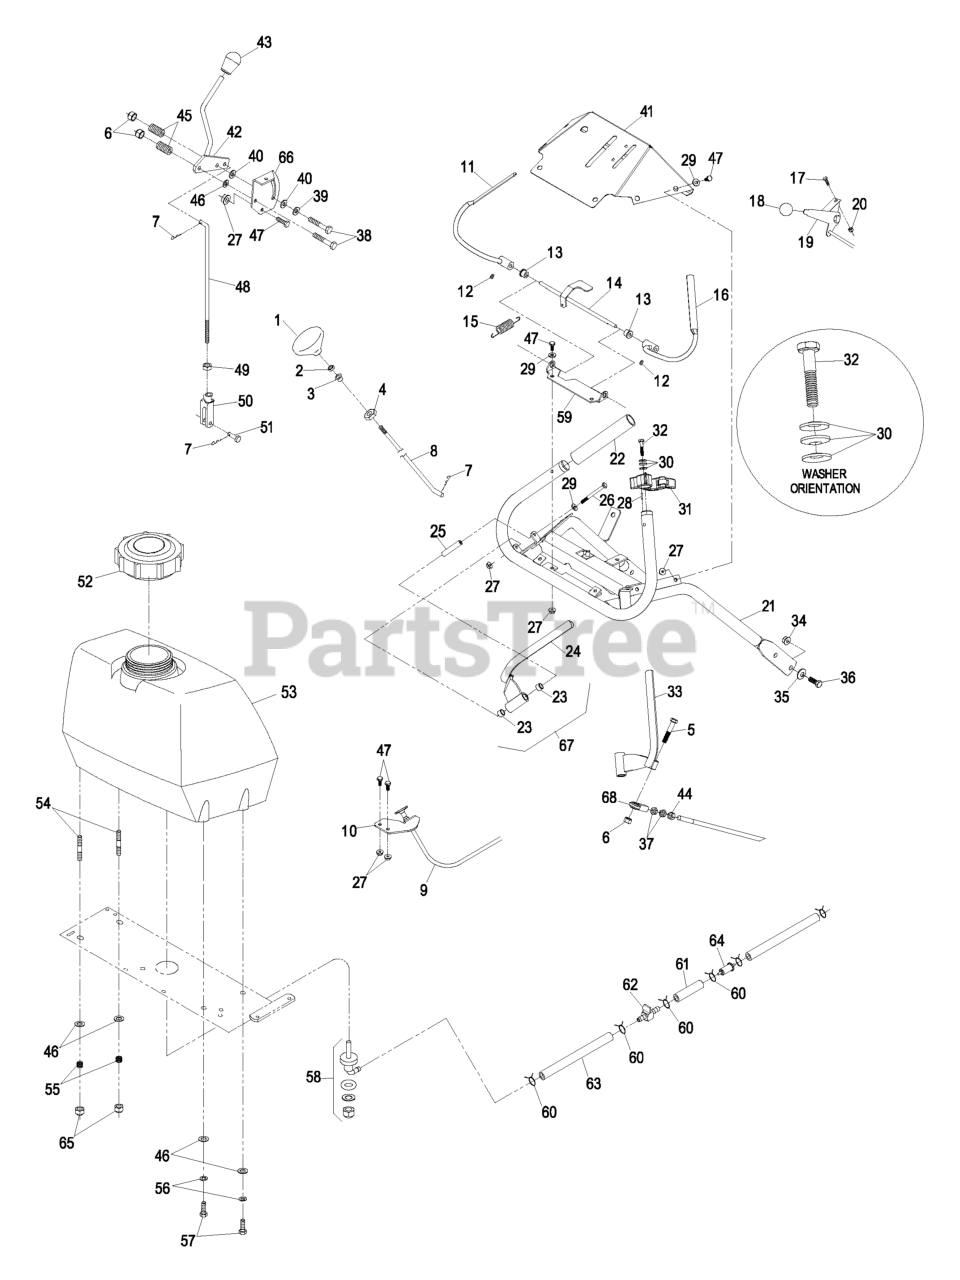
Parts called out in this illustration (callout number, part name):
1	KNOB-PUSH / PULL
2	NUT-JAM
3	BEARING-NYLON
4	NUT-PUSH
5	SCREW-HH
6	NUT-LOCK, NI
7	PIN-COTTER
8	LINKAGE,BLADE PUSH/PULL
9	CABLE-CHOKE
10	BRACKET-CABLE, CHOKE
12	SCREW-SET
13	BUSHING-NYLON
14	WLD,OPC LEVER AXLE
15	SPRING-EXTENSION
17	BOLT-CARR
18	KNOB-BALL
19	THROTTLE CABLE ASM
20	NUT-LOCK, NI
21	WLD,VH ECS HANDLE
22	GRIP-BAR, HANDLE
23	BUSHING-SLEEVE
25	BUSHING-LEVER, DRIVE
26	SCREW-HH
29	WASHER-FLAT
30	WASHER-SPRING
31	ASM,LATCH RH THUMB
32	SCREW-HH
34	NUT-HHF, WHIZ
35	WASHER-BELLEVILLE
36	SCREW-HH
37	NUT-HJ
38	SCREW-HH
39	WASHER-FRICTION
40	WASHER-FRICTION
41	ASM,CONSOLE W/DECALS
43	KNOB, FE.LCKG. BLACK
44	NUT-HEX
45	SPRING-COMPRESSION
46	WASHER-PLAIN
47	SCREW-HH
48	ROD-CONTROL, SPEED
49	NUT-JAM
50	YOKE-ADJUSTABLE
51	PIN-CLEVIS
52	CAP-FUEL, GAS
53	ASM,FUEL TANK W/B
54	STUD
55	SPRING-TANK, FUEL
56	WASHER-LOCK
57	SCREW-HH
58	FITTING-FUEL, BULKHEAD
59	BRACKET,OPC AXLE
61	HOSE-FUEL
62	VALVE-FUEL
63	HOSE-FUEL
64	Kawasaki Pn 41019-1055 Filter W/6" Fuel Line
65	NUT-LOCK, NI
66	BRACKET,SHIFTER SLIDE (PL
67	DRIVE LEVER-ASM, RH
68	JOINT-BALL, END
